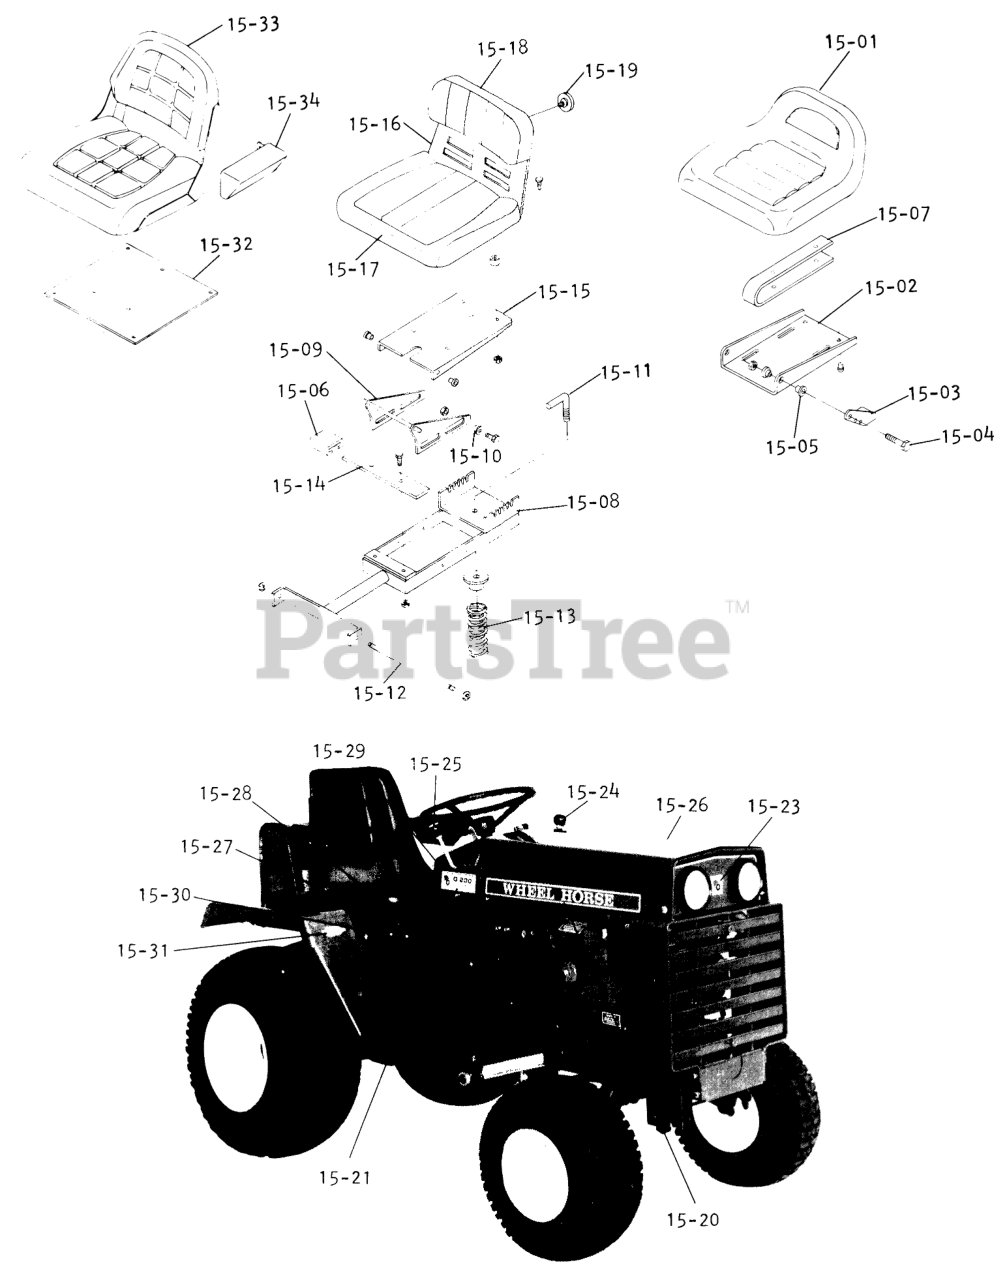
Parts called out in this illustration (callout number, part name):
15-01	Seat
15-02	Plate Seat Pivot
15-03	Bracket-Pivot RH
15-04	Bolt 5/16-18 x
15-05	Bushing
15-06	BUMPER-RUBBER
15-07	Spring
15-08	Seat Pivot Assembly
15-09	Seat Adjustment Assembly
15-10	SPACER
15-11	Rod-Adjusting
15-12	Rod-Pivot
15-13	Spring
15-14	Bar-Seat Stop
15-15	Seat Ad justing Plate
15-16	Seat Base Assy.
15-17	Cushion Seat
15-18	Back Cushion
15-19	Wing Head Stud
15-20	Decal
15-21	Decal-"D-160 Automatic"
15-22	Washer
15-23	Decal-Headlight Plate, (D-160)
15-24	Decal-Clutch Knob
15-25	Decal-Hydro Control Knob
15-26	Decal
15-27	Decal
15-28	Decal
15-29	Decal
15-30	Decal-Maintenance
15-31	Reflector
15-32	Seat Plate, D-200
15-33	Seat, (D-200)
15-34	Arm Rest-R.H.
